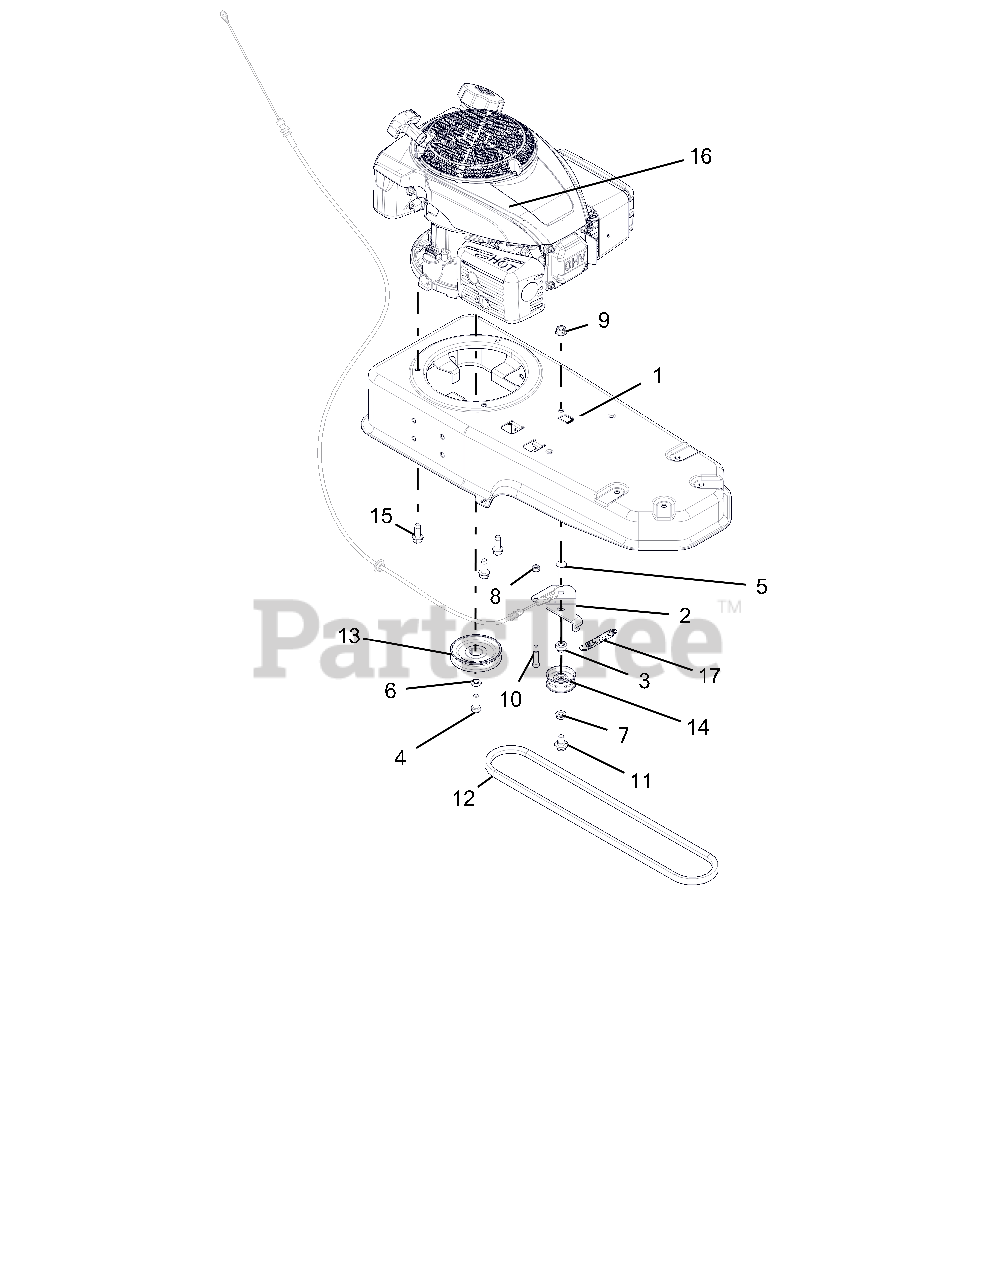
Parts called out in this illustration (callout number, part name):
1	KIT-FRAME W/SAFETY DECAL-TRIM
2	BRKT-IDLER STRING TRIMMER
3	SPCR, BRG .315X.500X.481X.281
4	BLT-HEX .38-24X1.0 YWZC GR5
5	BLT-RDHDSQSHK .31-18X1.75 YWZC
6	@WSHR-LK .38X.094 REG YWZC
7	@NUT-LK-CTR-FLG .31-18 YZ GR F
8	@NUT-LK-CTR .25-20 YWZC
9	NUT-LK-CTR-FLG .38-16 YWZC
10	SCR-SHLDR .25-20X1.00 -YWZC
11	BOLT-SHLDR .375-16X.150
12	V-BELT, HA-RAW EDGE
13	SHEAVE-ENGINE 3.50 ODX.87 WIDE
14	IDLER, FLAT - 1.875"
15	@SCR-TAP .38-16X1.00 HWH TR YZ
16	ENGINE, KOHLER XT6 149CC
17	SG-TENS .035X.45X2.75 WLD 3.5
